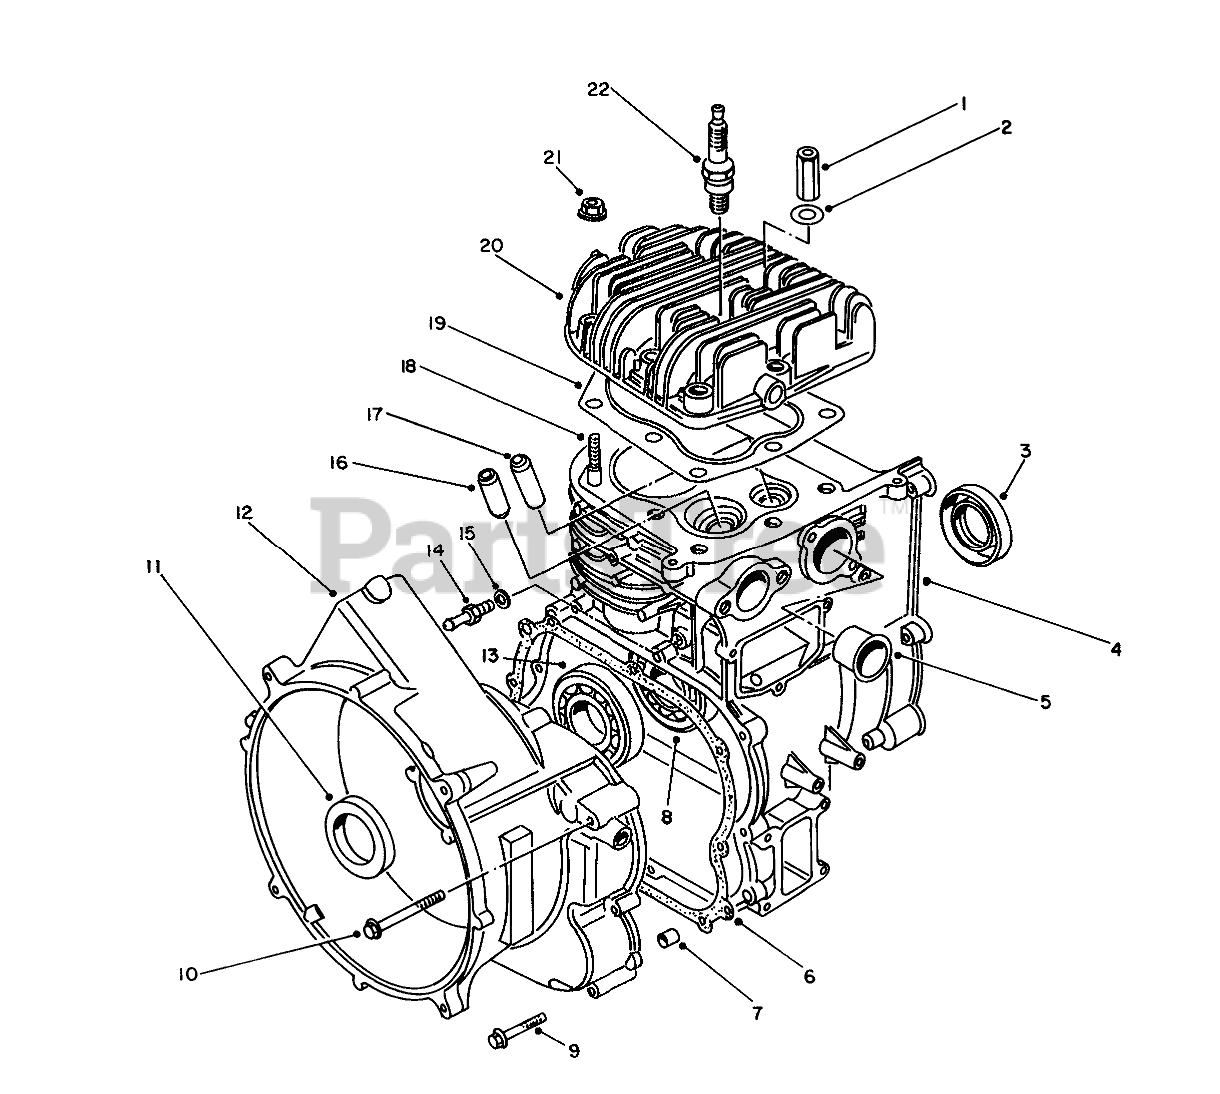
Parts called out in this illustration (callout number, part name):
2	Washer
3	OIL SEAL
4	Cylinder Assembly
5	Exhaust Guide
6	Gasket
8	Screw
11	OIL SEAL
12	Cover Assembly
13	Screw
14	Union
15	Gasket
16	Bolt
17	VALVE GUIDE
18	Stud Bolt
19	CYL HEAD GASKET
20	Head-Cylinder (53.8CC)
22	SPARK PLUG
